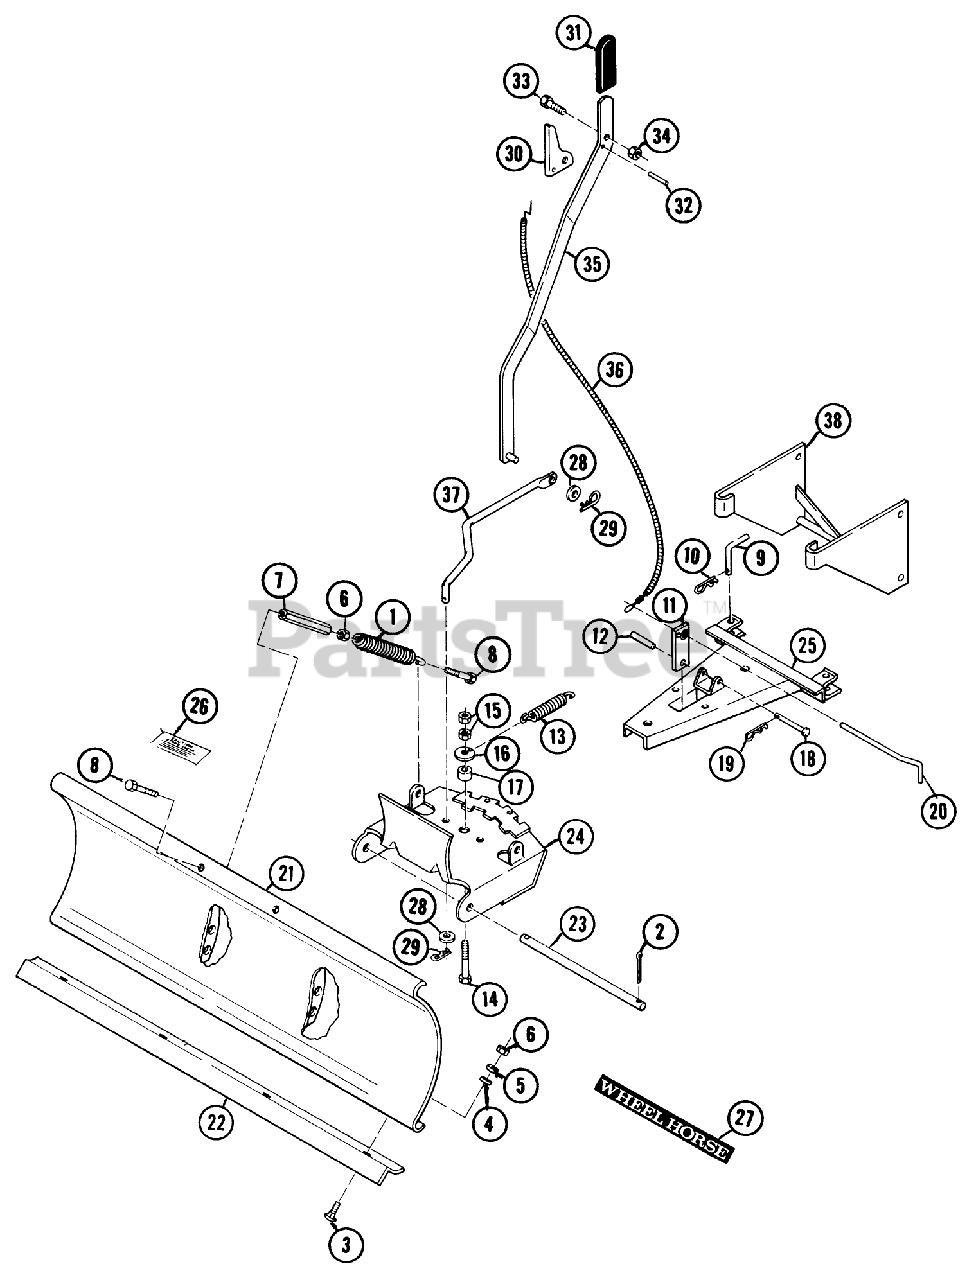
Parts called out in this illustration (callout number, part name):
1	Trip Spring
2	Cotter Pin, .156 x 1.25
3	Bolt, Carriage-5/8-16 x 1
4	Washer-3/8
5	Lockwasher 3/8
6	Nut, Hex 3/8-16
7	Coupler Nut
8	Bolt, Hex-3/8-16 x 1 1/2
9	"L" Shaped Pin
10	Hairpin Cotter
11	Pivot Bar Lock
12	Pin, Spring 1/4 x 1
13	Spring, Angle Lock
14	Bolt, Hex 3/4-10 x 4 1/2
15	Nut, Hex 3/4-10
16	Washer
17	Spacer
18	Clevis Pin
19	Hairpin Cotter
20	Handle,Angle Lock
21	Blade-48"
22	Wear Blade
23	Pivot Rod
24	Pivot Plate
25	Blade "A" Frame
26	Caution Decal
27	DECAL-WHEEL HORSE
28	Washer, STD. 5/8
29	Hairpin Cotter
30	Hand Lever (Index Release)
31	Hand Grip
32	Roll Pin .12 x 1/2
33	Nut 1/4-20
34	Locknut, 1/4-20
35	Index Lever
36	Cable Assembly
37	Index Rod
38	Mounting Bracket
